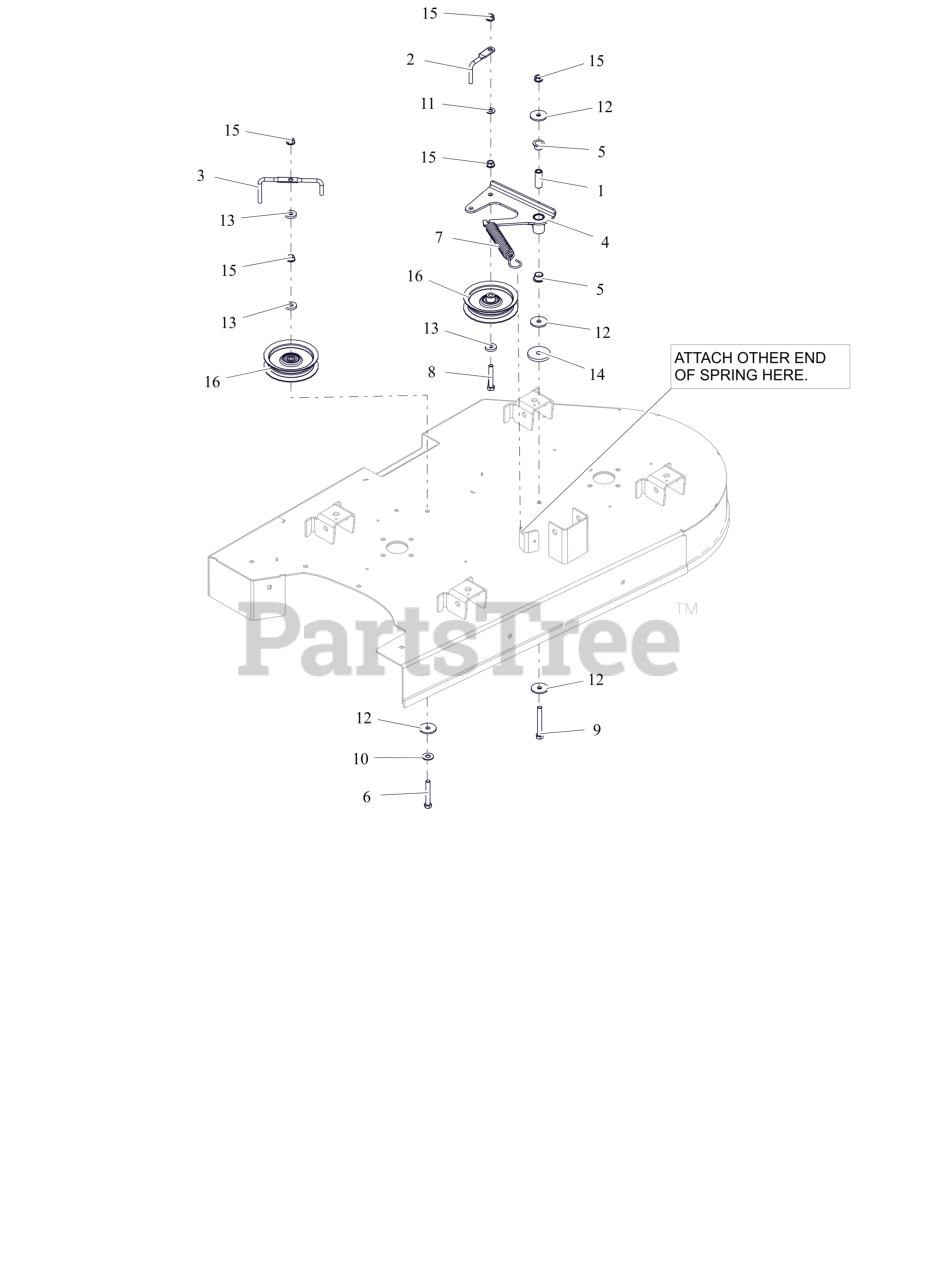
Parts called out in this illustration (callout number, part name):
1	SPACER, .375IDX.625ODX1.66 PM
2	WIREFORM-BELT FINGER
3	BELT FINGER
4	WLDMT, IDLER ARM (ORANGE)
5	BSHG-FLG, .625X.750X.500X1.00
6	BLT, HEX .38-16X2.50 G5 ZCC
7	SG-TENS .135X.98X6.0 WLD 62
8	BLT,HEX .38-16X2.25 G5 ZCC
9	BLT, HEX .38-16X3.00 G5 ZCC
10	WSHR,FLT .438X1.00X.083 ZCC
11	WSHR,FLT .406X.812X.065 ZCC
12	WSHR, FLT .380X1.50X.125 ZCC
13	WSHR, FLT .406X1.00X.188 ZCC
14	WSHR, FLT .469X2.00X.250 ZCC
15	NUT-LK-CTR-FLG .375-16 GF ZCC
16	IDLER, FLAT - 4.06" X .75"
